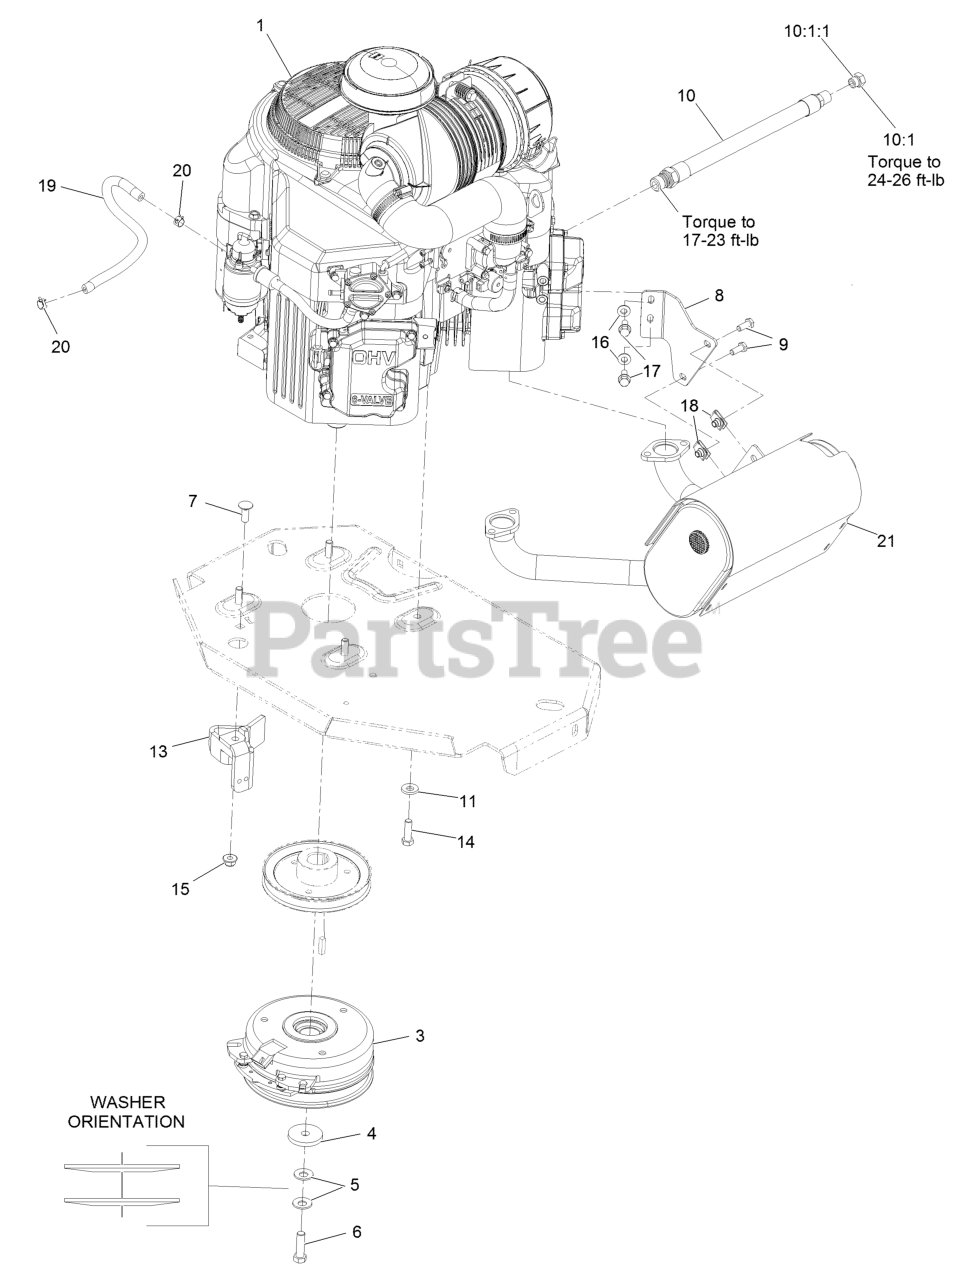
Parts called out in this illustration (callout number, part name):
4	WASHER-CLUTCH
5	WASHER-SPRING
6	SCREW-HH 7/16-20 X 1 1/2 W/LOCTITE
7	SCREW-CARR
8	BRACKET-MUFFLER
9	SCREW-HH
10	ENGINE OIL DRAIN HOSE ASM
10:1	PLUG-HH
10:1:1	O-RING
11	WASHER-BELLEVILLE
13	CLUTCH-ANCHOR
14	SCREW-HH
15	NUT-HF, NI
16	WASHER-SPRING
17	SCREW-HHF
19	HOSE-FUEL
20	CLAMP-HOSE
21	MUFFLER
